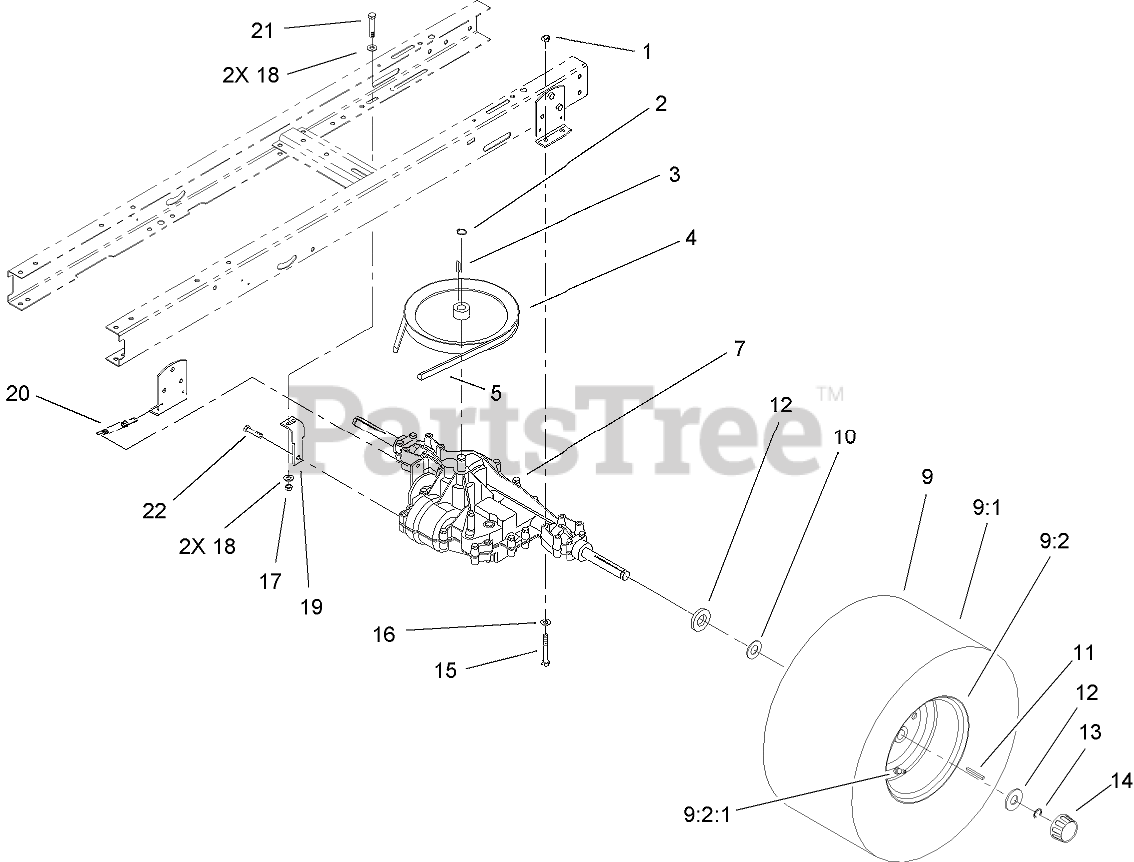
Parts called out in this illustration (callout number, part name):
1	NUT-LOCK, NI
2	RING-SNAP, EXTERNAL
3	KEY-WOODRUFF
4	PULLEY-TRANSMISSION
5	V-BELT
7	TRANSAXLE ASM
9	REAR WHEEL & TIRE ASM
9:1	TIRE
9:2:1	STEM-VALVE
10	WASHER-THRUST
11	KEY-SQUARE
12	WASHER-PLAIN
13	E-RING
14	CAP-HUB
15	SCREW-HH
16	WASHER-PLAIN
17	NUT-LOCK, NI
18	WASHER-PLAIN
19	STRAP-TORQUE
20	SPRING-RETURN, BRAKE
21	SCREW-HH
22	SCREW-HWHTF
